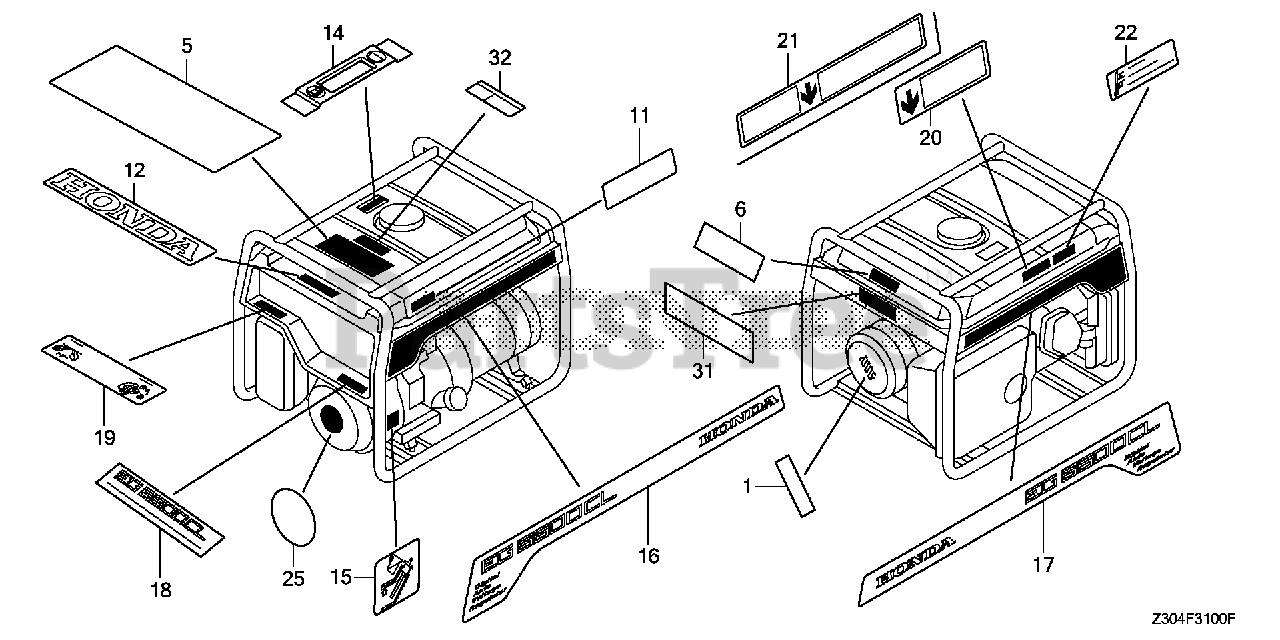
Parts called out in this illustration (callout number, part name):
1	MARK, VOLT
5	LABEL, OPERATOR WARNING (E)
6	MARK, SPEC
11	LABEL, OIL ALERT
12	MARK, HONDA
14	PLATE, FUEL INDICATION
15	MARK, OIL CHECK
16	MARK, R. EMBLEM (EG6500CL)
17	MARK, L. EMBLEM (EG6500CL)
18	MARK, FR. EMBLEM (EG6500CL)
19	MARK, OPERATION
21	LABEL, EX. WARNING
25	MARK, HONDA
32	LABEL, FUEL WARNING (ENGLISH)
